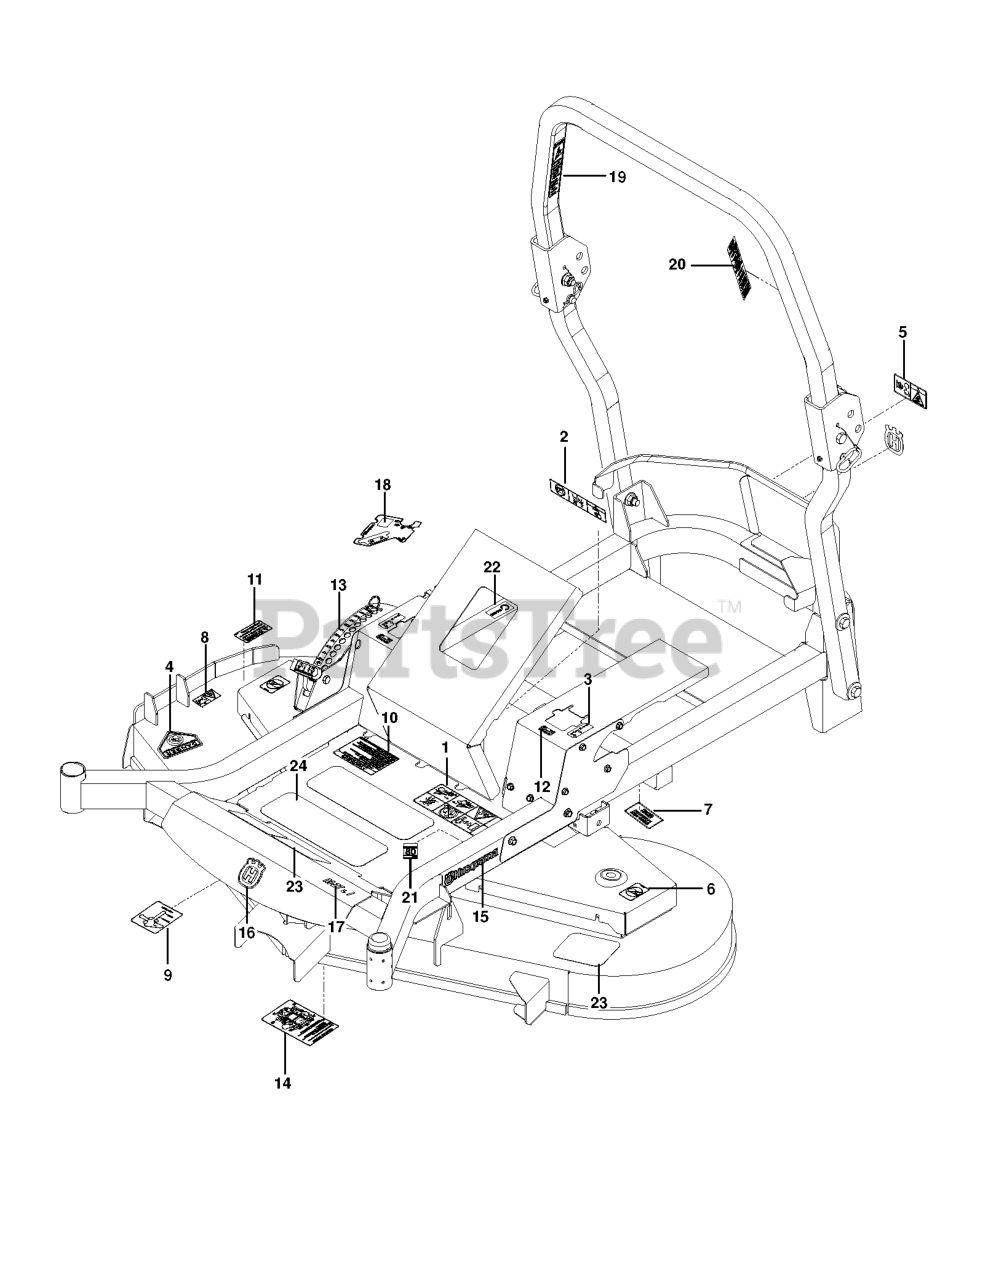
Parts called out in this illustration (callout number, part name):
1	DECAL, WARNING
2	EURO DECAL-BATTERY WARNIN6
3	DECAL, MOTION CONTROL
4	DECAL, CPSC
5	DECAL, BELT DRIVE
6	DECAL, NO STEP
7	HG_DECAL, ZT-3400
8	DECAL, EURO SEVERING
9	DECAL, BELT ROUTING
10	DECAL, WARNING
11	DECAL, CAUTION
12	DECAL, F.S.T.
13	DECAL, HEIGHT ADJUST
14	DECAL, SERVICE
15	RP.DECAL.BADGE.170MM.TEXTLOGO
16	DECAL.AUGER.HUSQ.CROWN.SNOW
17	DECAL.ZTR.MZT52.HUSQVARNA
18	DECAL, CONSOLE HUS
19	DECAL, ROPS, WARNING
20	DECAL ROPS
21	DECAL 80 DBA
22	DECAL, ECM, AUSTRALIA
24	ANTI-SKID PAD
